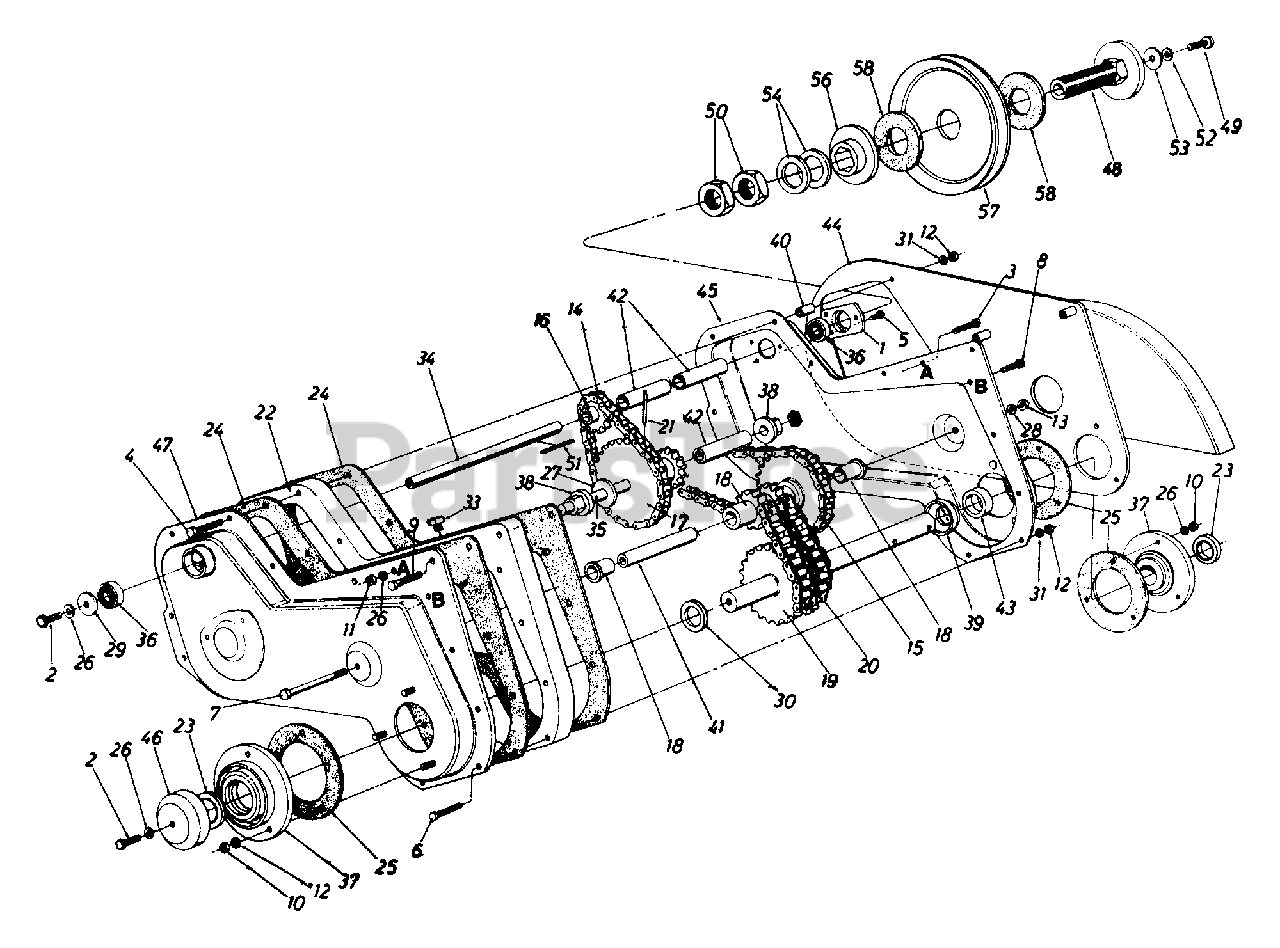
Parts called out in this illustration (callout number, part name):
1	Bearing Housing 1-3/8" Dia.
2	Hex Bolt 5/16-18 x .88" (Spec.)
3	Hex Bolt 5/16-18 x 1.5" Lg.
4	Hex Bolt 1/4-20 x 2.75" Lg.
5	Hex S-Tap Scr. 1/4-20 x .5" Lg.
6	Hex Bolt 1/4-20 x 1.5" Lg.
7	Hex Bolt 3/8-16 x 4.5" Lg.
8	Hex Scr. 1/4-20 x 1.5" Lg.
9	Hex TT-Tap Scr. 5/16-18 x 1.75"
10	Hex L-Nut 5/16-18 Thd.
11	Hex Nut 5/16-18 Thd.
12	Hex Nut 1/4-20 Thd.
13	Hex Nut 3/8-16 Thd.
14	#41 Chain 1/2" Pitch x 34 Links - Endless
15	#42 Chain 1/2" Pitch x 48 Links - Endless
16	Sprocket 10 Tooth .5" Pitch
17	10 & 28 Teeth Sprocket Ass'y.
18	8-2 & 28 Sprocket Sleeve Ass'y.
19	18-2 Sprocket Shaft Ass'y.
20	#50-2 Chain 5/8" Pitch x 28 Links - Endless
21	Spring Pin Spir. 1/4" Dia. x 1.5" Lg.
22	Spacer Block - Tiller Housing
23	Oil Seal 1-1/4" Dia.
24	Gasket for Tiller Housing
25	Gasket for Brg. Housing
26	L-Wash. 5/16" I.D.
27	Fl-Wash. .64" I.D. x 1.24" O.D.
28	L-Wash. 3/8" I.D. - H.D.
29	Fl-Wash. .344" I.D. x 1.125"
30	Special Washer
31	L-Wash. 1/4" I.D.
33	Vent Plug
34	Jack Shaft .525" I.D. x 7.78"
35	Sprocket Shaft .63" Dia. x 5"
36	Ball Brg. .62" I.D. x 1.38" O.D.
37	Bearing Housing - 1-1/4"
38	Hex Flange Brg.
39	Spacer 1.25" I.D. x 2.0" O.D.
40	Spacer .9" Lg.
41	Spacer 3.44" Lg.
42	Spacer .62" I.D. x .88" O.D. x 1.56" Lg.
43	Spacer .5" Lg.
46	Dust Cap
49	Hex Bolt 5/16-18 x 1.25" Lg. Grade 5
50	Hex Jam Nut 1.0-14 x 28 Thd.
51	Sq. Key 3/16 x 1.5" Lg.
52	L-Wash. 5/16" I.D.
53	Fl-Wash. .344" I.D. x 1.125"
54	Bell-Wash. 1.0" I.D. x 2.0"
56	Floating Disc 3-1/4" O.D.
57	5/8 V-Pulley 1.5" I.D. x 6.5"
58	Friction Pad 3-1/4" O.D. x 1-3/8" I.D.
